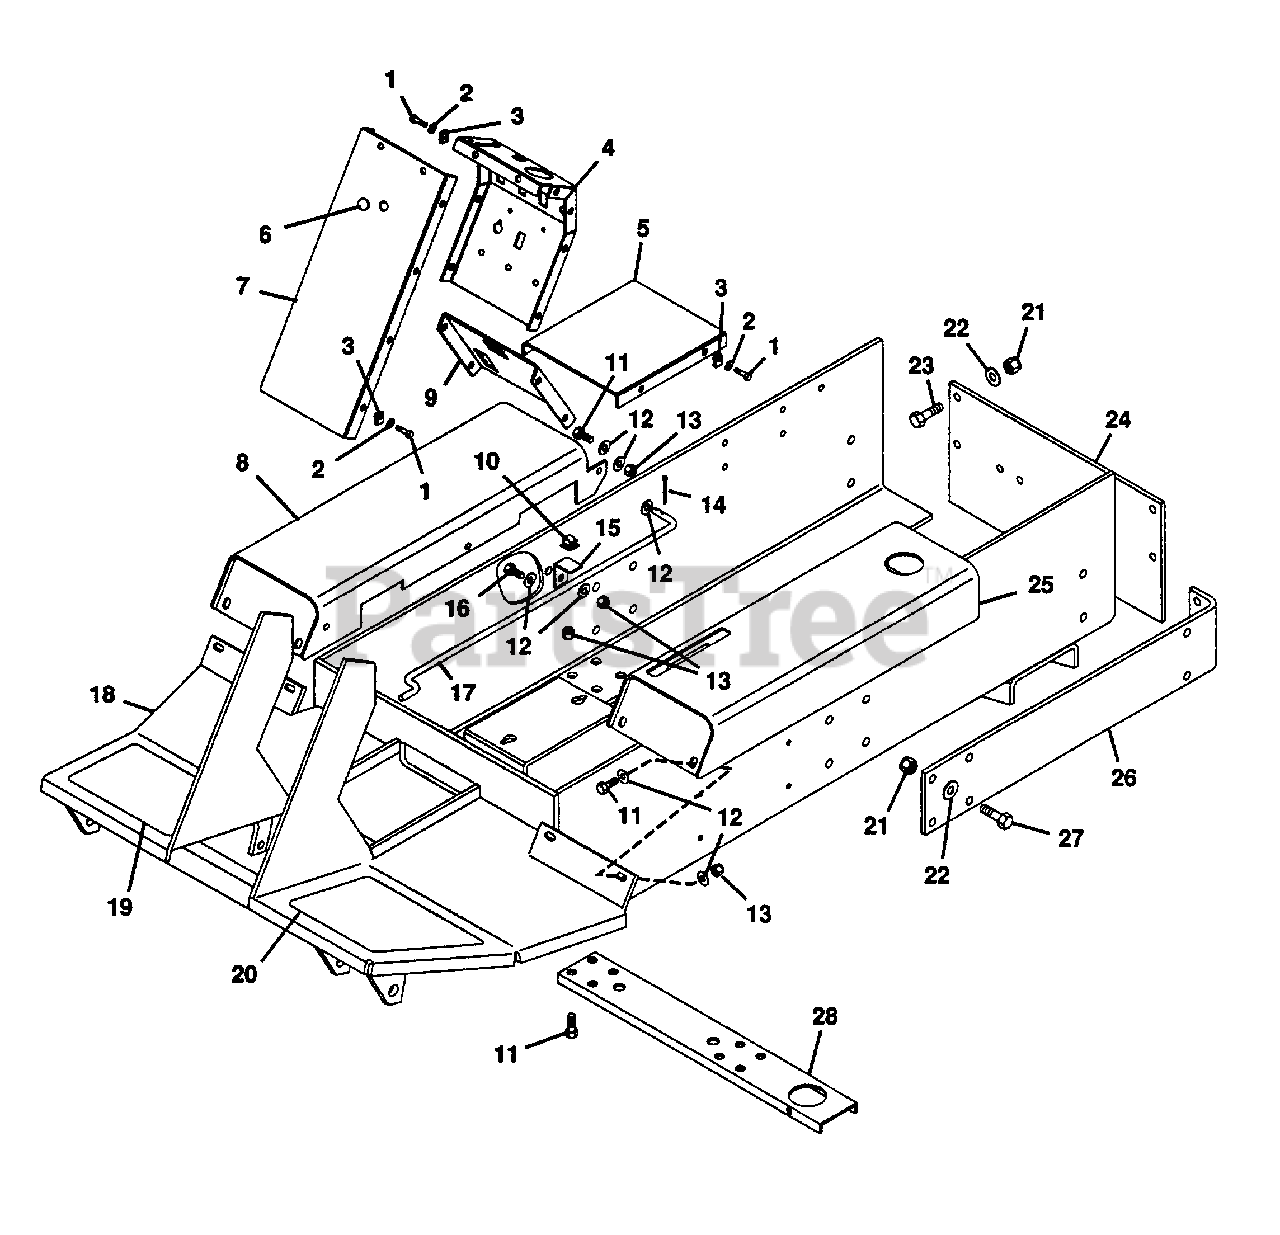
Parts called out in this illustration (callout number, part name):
1	Screw, Machine 1/4-20 PHD
2	Washer, Flat .281x.625x.065
3	Nut, Retainer
4	Panel, Instrument Silk Screen
5	Plate, Access Silk Screen
6	Plug, Hole
7	Panel, Front Silk Screen
8	Fender, Silk Screen R.H.
9	Panel, Brake Lock Silk Screen
10	Clip, Wire
11	Bolt, Hex 3/8-16x.875
12	Washer, Flat .406x.812x.065
13	Nut, Lock 3/8-16
14	Pin, Cotter .094x.75
15	Bracket, Stay Rod
16	Bolt, Hex 3/8-16x1.00
17	Rod, Stay
18	Weldment, Frame
19	Cover, R.H. Foot
20	Cover, L.H. Foot
21	Nut, Lock 1/2-13
22	Washer, Flat .531x1.062x.095
23	Bolt, Hex 1/2-13x1.50
24	Plate, Bumper
25	Fender, Silk Screen L.H.
26	Bumper
27	Bolt, Hex 1/2-13x1.25
28	Brace, Frame
